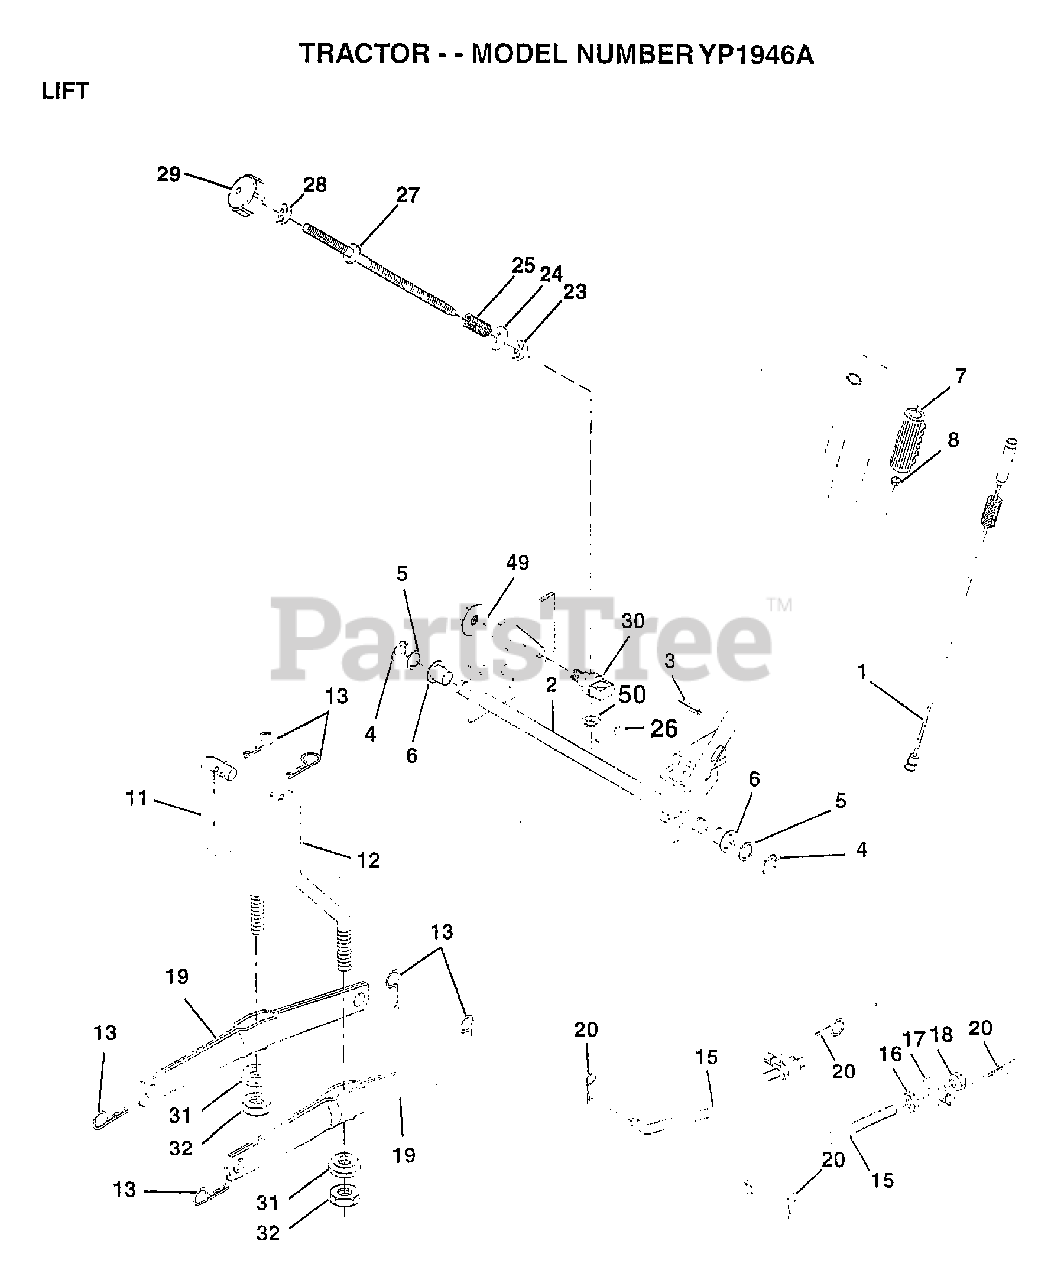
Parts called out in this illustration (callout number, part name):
1	WIRE ASM W.SPRING
2	SHAFT ASM LFT LH
3	PIN GROOVE
5	WASHER
6	NYLON BEARING
7	GRIP HANDLE
15	LINK.FRONT
16	NUT
17	TRUNION
18	NUT.LK.W/WSH.1/2.
19	ARM SUSP REAR
20	RETAINER.SPRING
23	NUT T
24	WASHER
25	SPRING T
28	NUT
29	KNOB INF 3/8-16
30	TRUNNION
31	BEARING PVT LH
32	NUT.CROWNLOCK.3/8
36	POINTER-INDICAT
37	"PLUG,HOLE"
38	SCREW
40	WASHER
41	HEIGHT INDICATOR
49	NUT.HXFLG.LOCK.
50	NUT PUSH M
